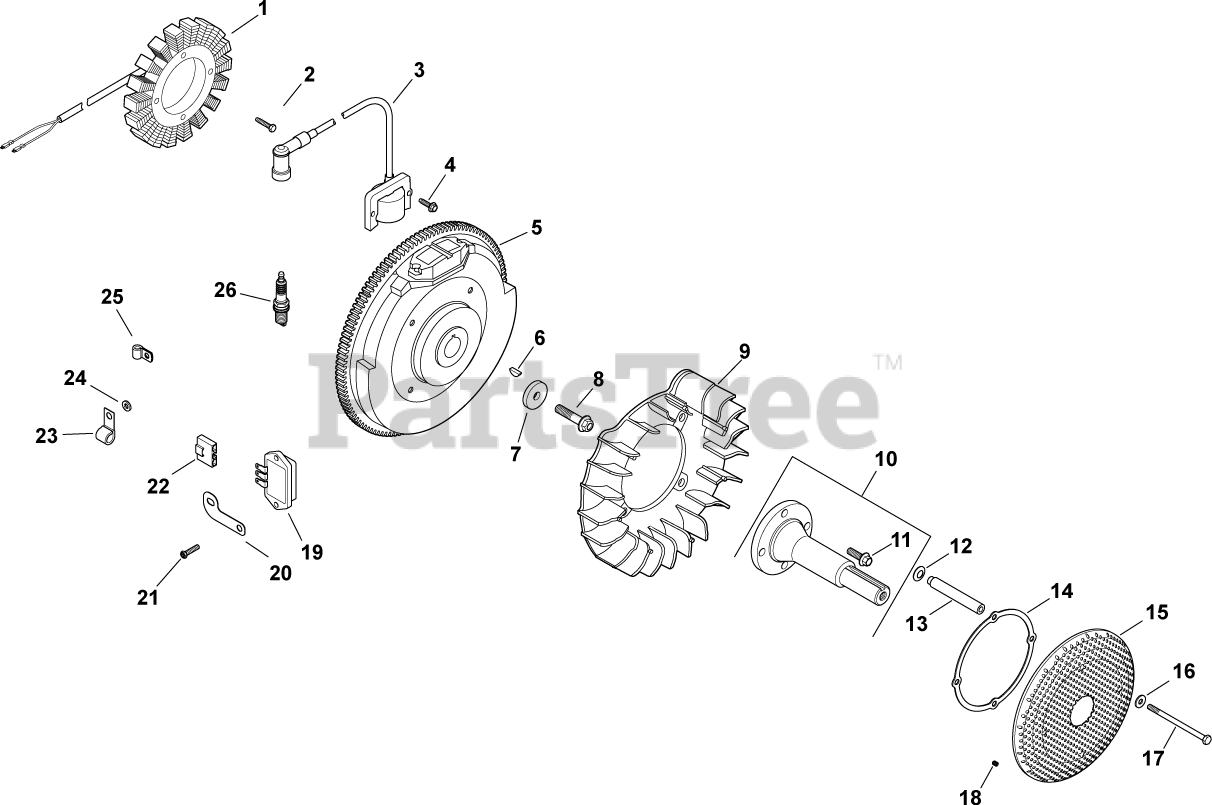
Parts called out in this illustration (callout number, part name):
1	KIT, 15 / 20 AMP STATOR
2	SCREW, M5X0.8X25 - (#25086402S)
3	KIT, MODULE IGNTN (CDI FIXED)
4	SCREW, FLG THD FRM M5X.8X20-(#25086399S)
6	KEY, 3/16" X 5/8"
7	WASHER, FLAT 13/32"
8	SCREW, FLG M10X1.5X45 - (#25086361S)
9	FAN - USE (#24 157 11-S)
10	SHAFT, FRONT DRIVE
11	SCREW, FLG M8X1.25X25
12	WASHER, SPRING 10 MM
14	RING, SUPPORT USE 25 141 08-S
15	SCREEN, GRASS
16	WASHER, FLAT 1/4" (O.D. 5/8")
17	SCREW, SOCKET TRUSS HD CAP
18	SCREW, SKT SET #10-24X1/4"
19	REGULATOR/RECTIFIER
20	BRACKET, GROUND STRAP USE 24 518 12-S
21	SCREW, HEX FLANGE HI-LO
22	CONNECTOR
23	CLIP, CABLE
24	WASHER, FLAT 1/4" (O.D. 1/2")
26	PLUG, SPARK (STD)
2513212-S	PLUG, SPARK (PRO SERIES)
